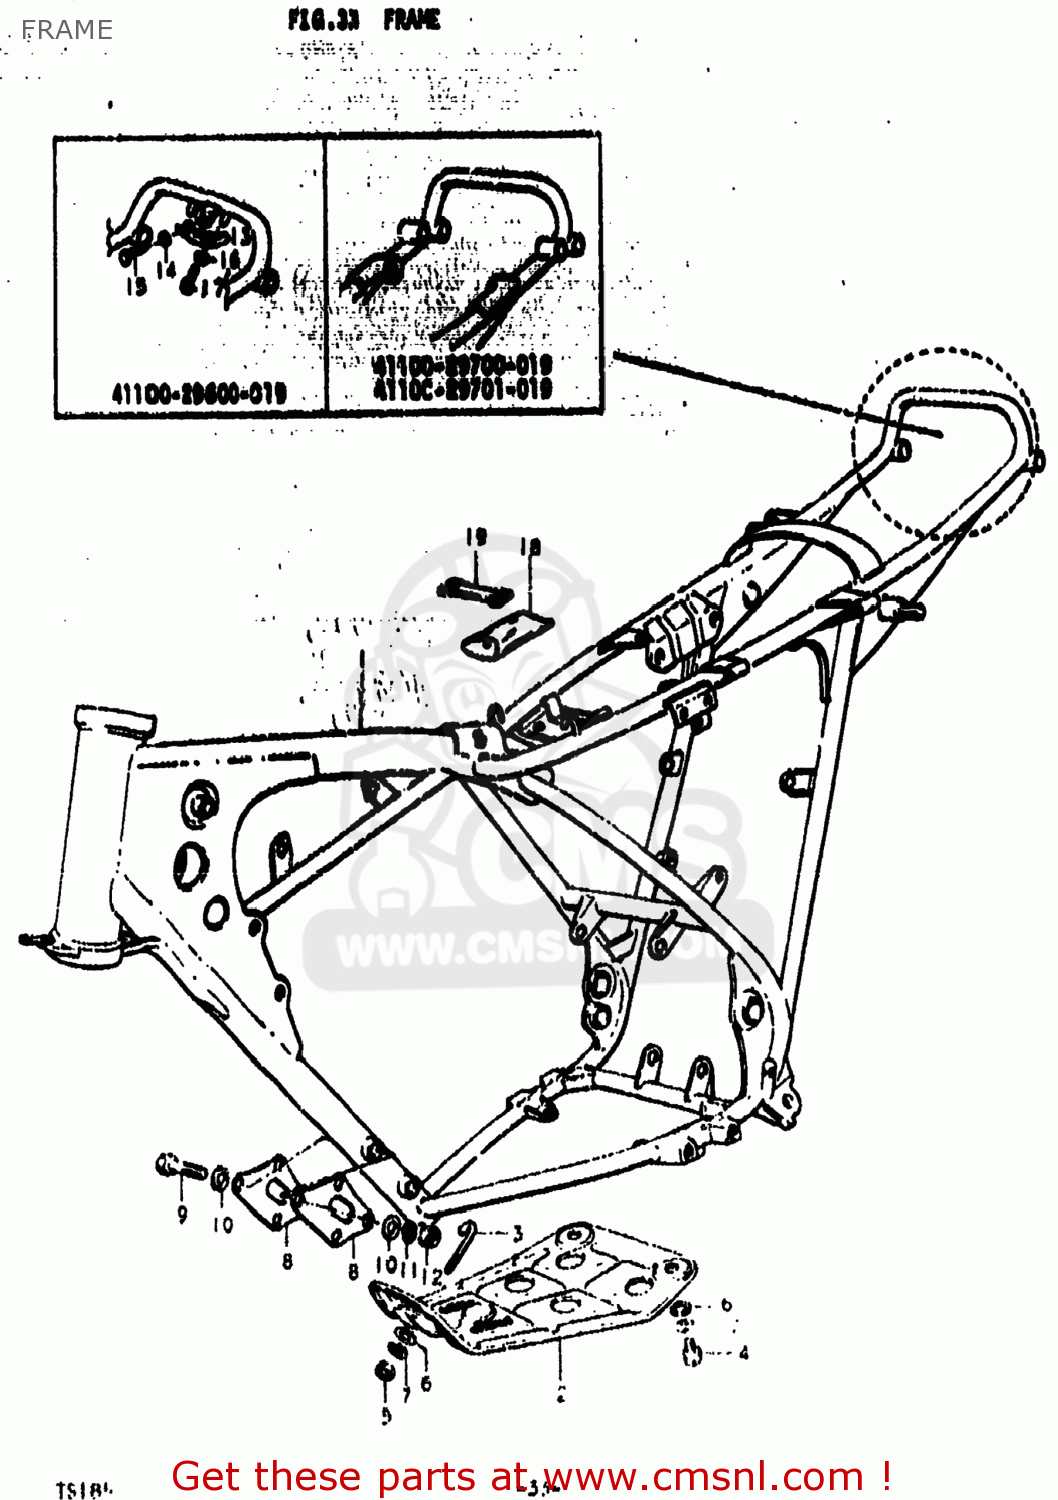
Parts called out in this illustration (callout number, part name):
1	FRAME
2	PROTECTOR,ENGINE
3	BRACKET,ENGINE PROTECT
4	BOLT
5	NUT
6	WASHER
7	LOCK WASHER
8	PLATE,ENGINE MOUNTING
9	BOLT
10	WASHER
11	LOCK WASHER
12	NUT
14	LOCK WASHER
15	BOLT
16	LOCK WASHER
17	BOLT
18	TOOL SET
19	BAND
